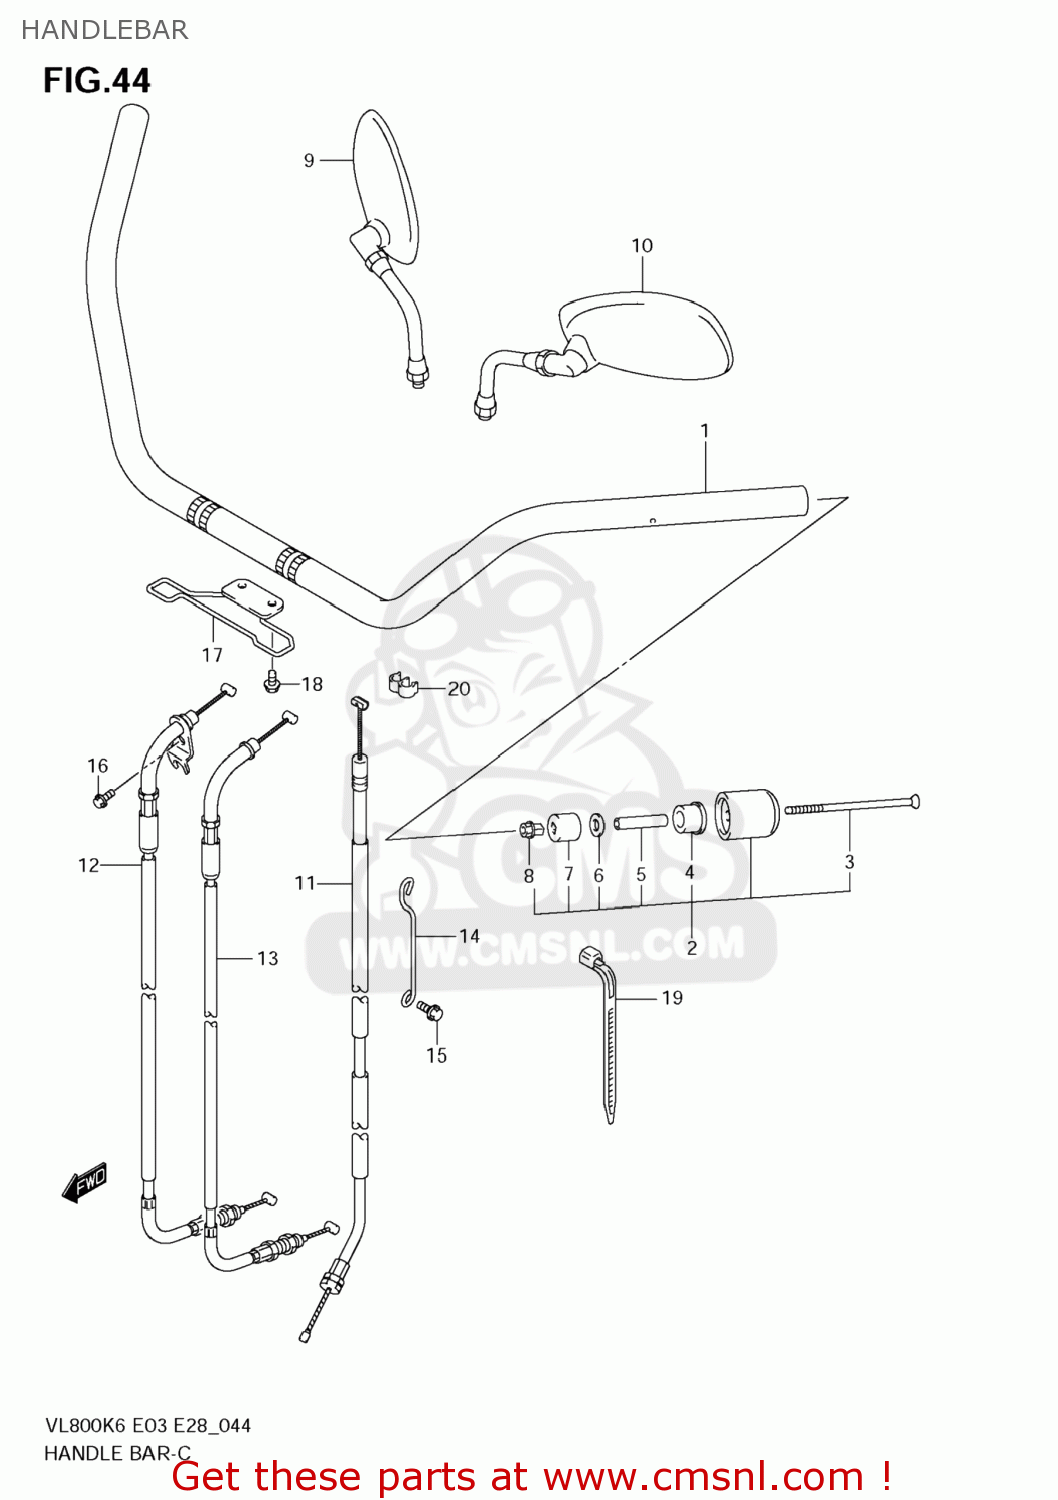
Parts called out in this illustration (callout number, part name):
1	HANDLEBAR
2	BALANCER SET,H
3	SCREW(6X127)
4	EXPANDER,HANDLE BALANCER NO.2
5	SPACER,EXPANDER
6	WASHER(6.5X16X4)
7	EXPANDER,HANDLE BALANCER
8	NUT,HANDLE BALANCER
9	MIRROR ASSY,RE
10	MIRROR ASSY,RE
11	CABLE ASSY,CLUTCH
12	CABLE ASSY,THROTTLE NO.1
13	CABLE ASSY,THROTTLE NO.2
14	GUIDE,THROTTLE CABLE
15	SCREW(5X10)
16	BOLT
17	GUIDE,CABLE
18	BOLT
19	CLAMP(L:190)
20	CLIP
